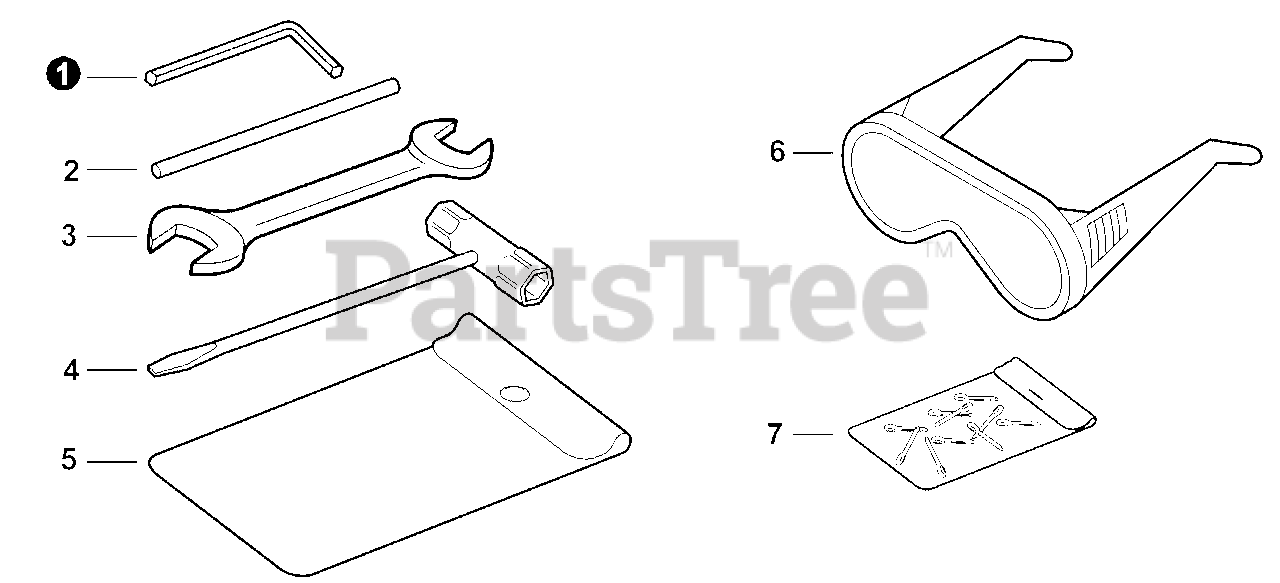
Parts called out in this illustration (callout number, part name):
1	WRENCH, T27 80×30
2	TOOL, LOCKING 5×120 MM
3	SPANNER 8×10
4	T-WRENCH 17x-19 L200
5	BAG, TOOL
6	GLASSES, SAFETY
7	PIN, COTTER 2×22
